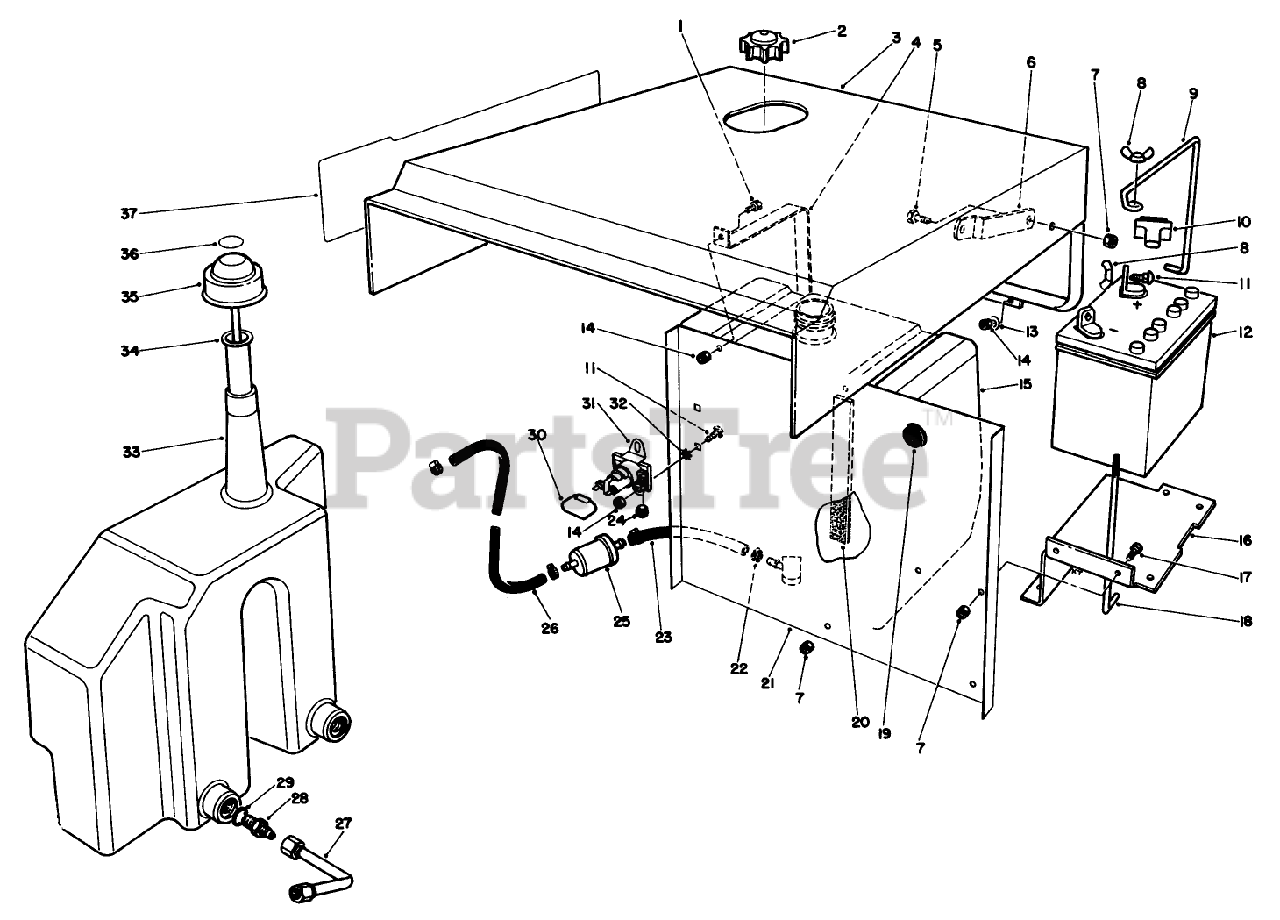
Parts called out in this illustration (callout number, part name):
1	SCREW-HH
2	GAS CAP
5	SCREW-HH
6	UPPER HOOD STOP
7	NUT-LOCK, NI
8	NUT-WING
9	BATTERY CLAMP
10	BOOT-TERMINAL
11	BOLT-CARR
12	SEE SB MISC 14
13	WASHER-FLAT
14	NUT-LOCK, NI
17	SCREW-HH
18	ROD-SUPPORT, BATTERY
19	GROMMET
20	TANK SPONGE
24	NUT-HEX
27	TUBE ASM
28	FITTING-STRAIGHT
29	O-RING
32	WASHER-LOCK/EXT
33	OIL RESERVOIR
34	SCREEN-FILLER
35	CAP WA
36	OIL DECAL
